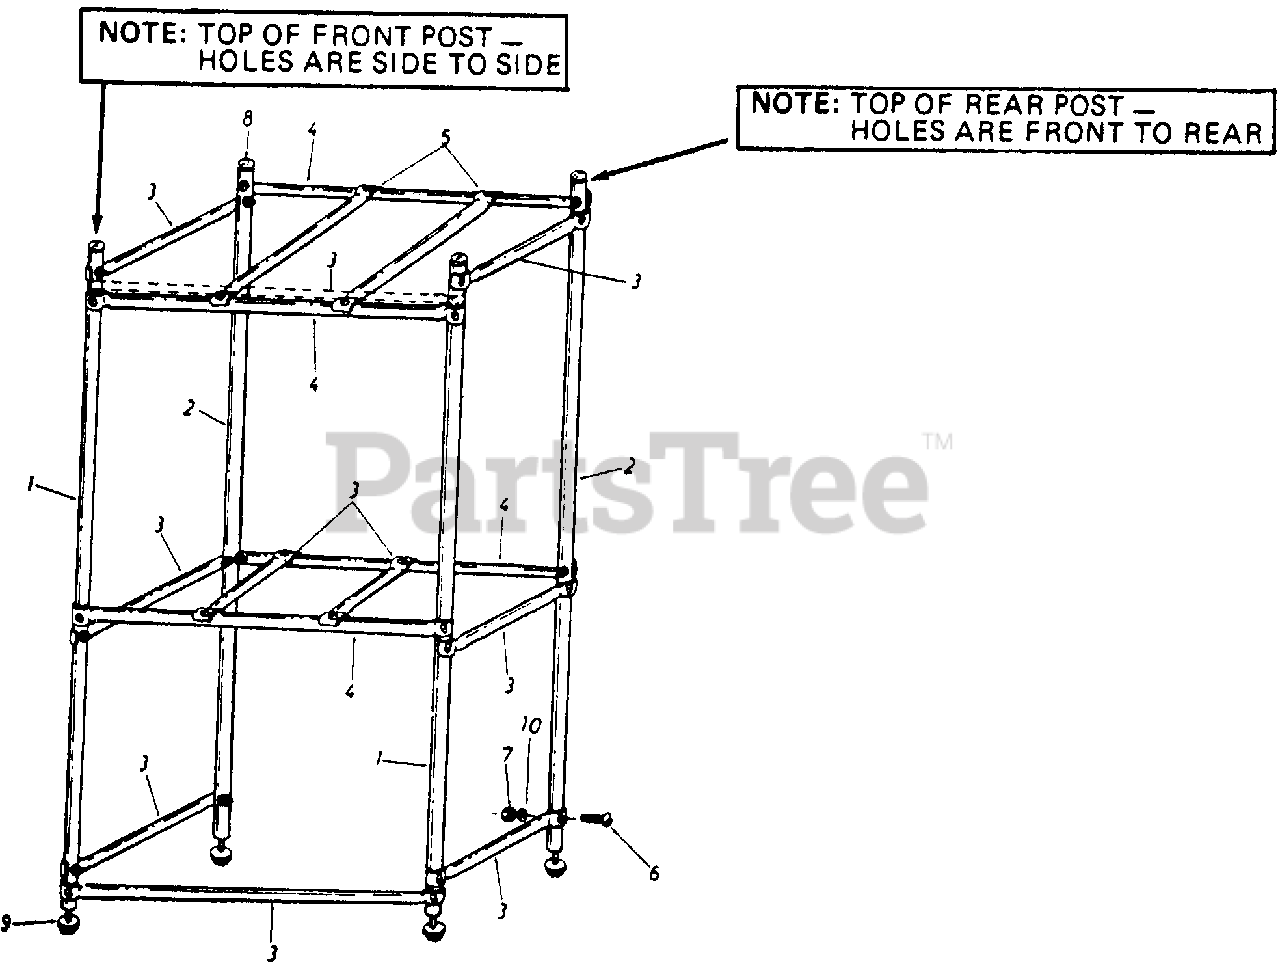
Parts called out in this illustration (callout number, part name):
3	Cross Brace w/o Center Holes 31" Lg.
6	Truss. Mach. Screw 1/4- 20 x 1 1/2" Lg.
7	Hex Nut 1/4-2 Thd. 32
8	1" Tubing Plug
9	1" Swivel Glide
10	Lock Washer 1/4" I.D. 32
